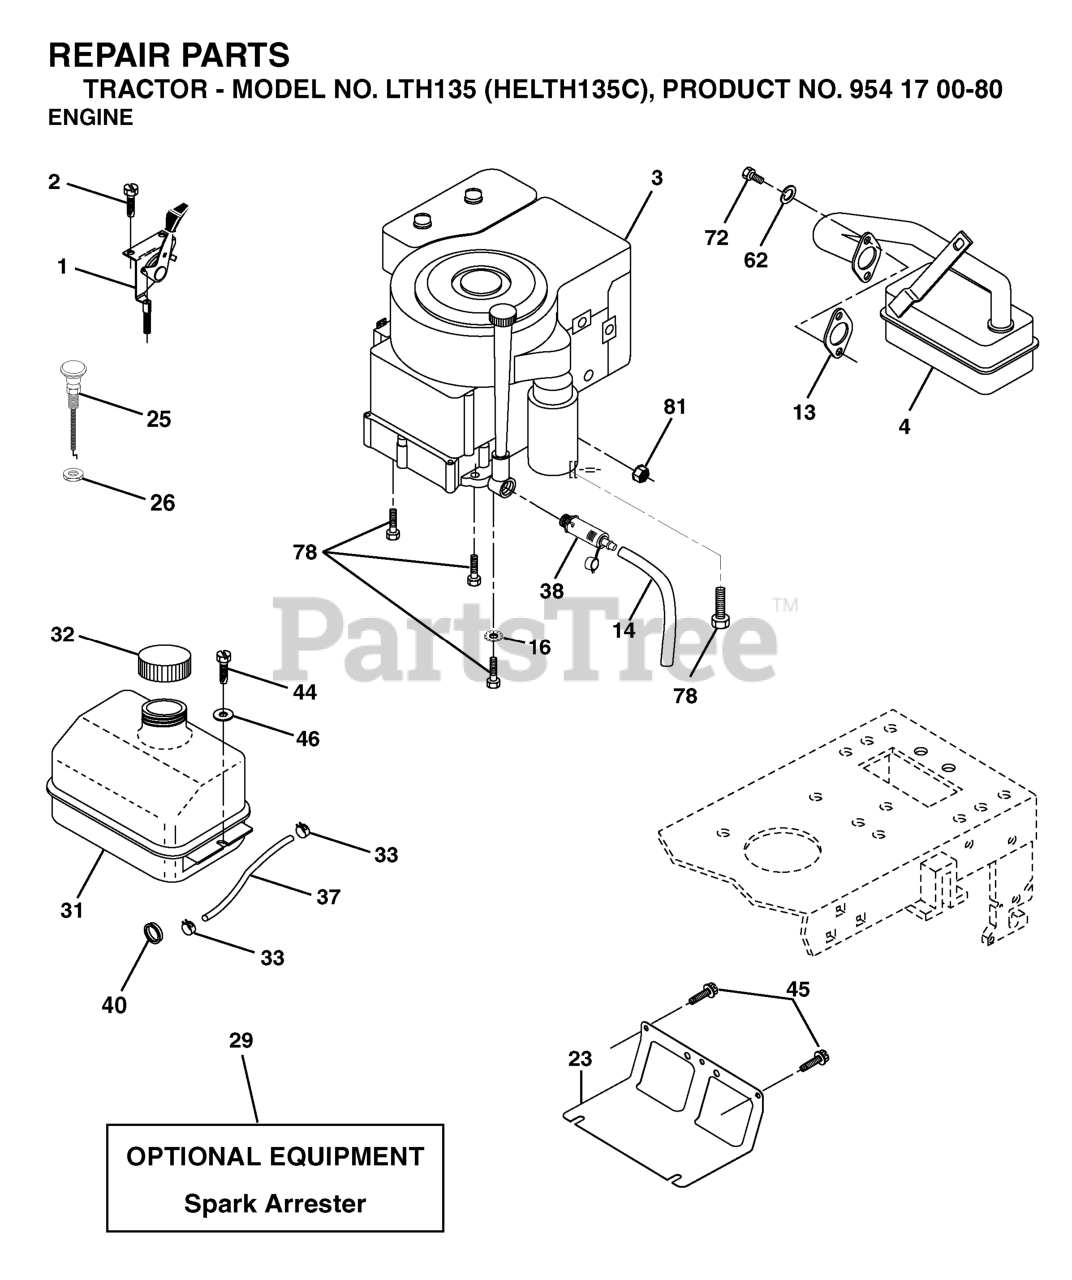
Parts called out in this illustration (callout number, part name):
1	CONTROL.THROTTLE/CHOKE.BLACK
2	SCREW
4	MUFFLER.LT.BRIGGS.14HP.IC/OHV
13	REPL BY 532 27 22-93
14	TUBE, DRAIN OIL ASM.
16	LOCKWASHER
23	SHIELD.BROWNING.DBR.GUARD
26	Nut Keps 3/8 - 24 UNF
29	KIT.SPARK ARRESTOR 794945 B&S
31	TANK FUEL LT
32	FUEL CAP
33	HOSE CLAMP
37	LINE.FUEL.20
38	PLUG DRAIN OIL EASY
40	BUSHING.SNAP.NYL.BLK.
44	SCREW HEXWSHR 1/4-20X3/4
45	SCREW, 3/8-16X3/4
62	WASHER.LOCK.HVY.HLCL.SPR.5/16
72	SCREW
78	SCREW.3/8-16
81	NUT
